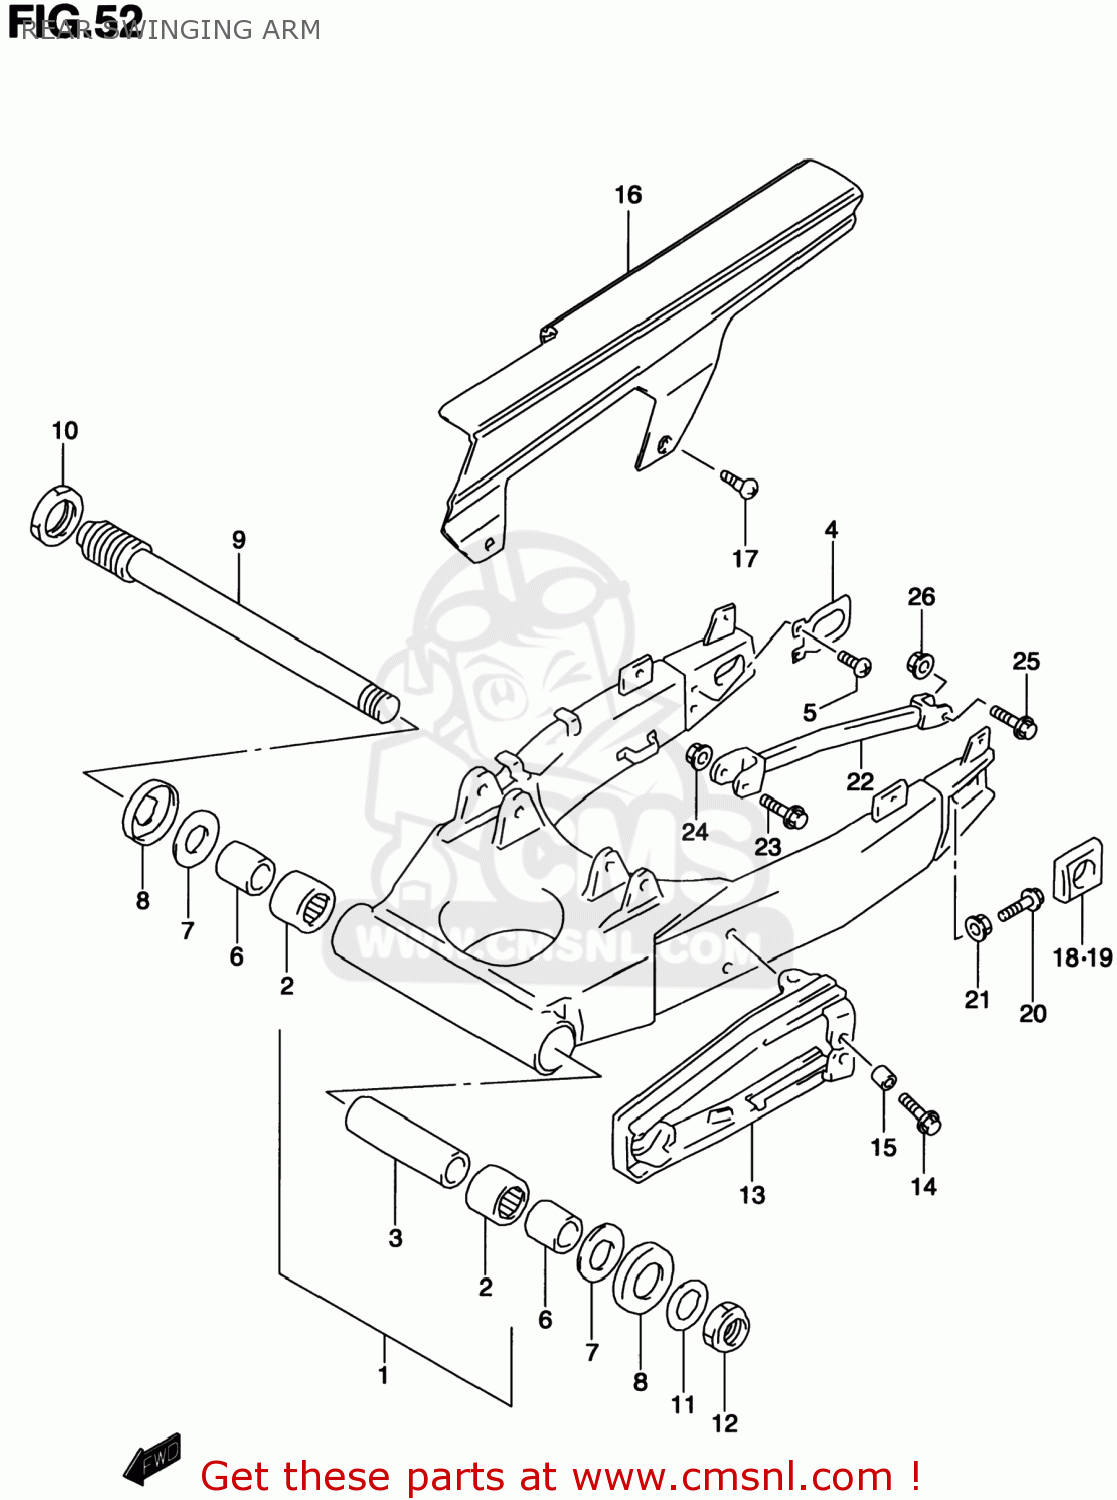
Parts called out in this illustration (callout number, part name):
1	SWINGINGARM ASSY,RR
2	BEARING(30X40X25)
3	SPACER,REAR SWING PIVOT,CENTER
4	PLATE,RR SWING ARM BRKT
5	SCREW
6	SPACER,REAR SWING ARM PIVOT
7	WASHER
8	DUST SEAL,RR SWGARM PIVOT
9	SHAFT,RR SWINGINGARM PIVOT
10	NUT,RR SWGARM PIVOT BOLT
11	WASHER(25.2X42X3.2)
12	NUT
13	BUFFER,CHAIN TOUCH DEFENSE
14	BOLT(6X20)
15	SPACER(6.5X9X5)
16	CASE,CHAIN
17	SCREW(6X16)
18	ADJUSTER,CHAIN,R
19	ADJUSTER,CHAIN,L
20	BOLT(8X50)
21	NUT
22	TORQUELINK,RR
23	BOLT(8X44)
24	NUT
25	BOLT(10X37)
26	NUT
